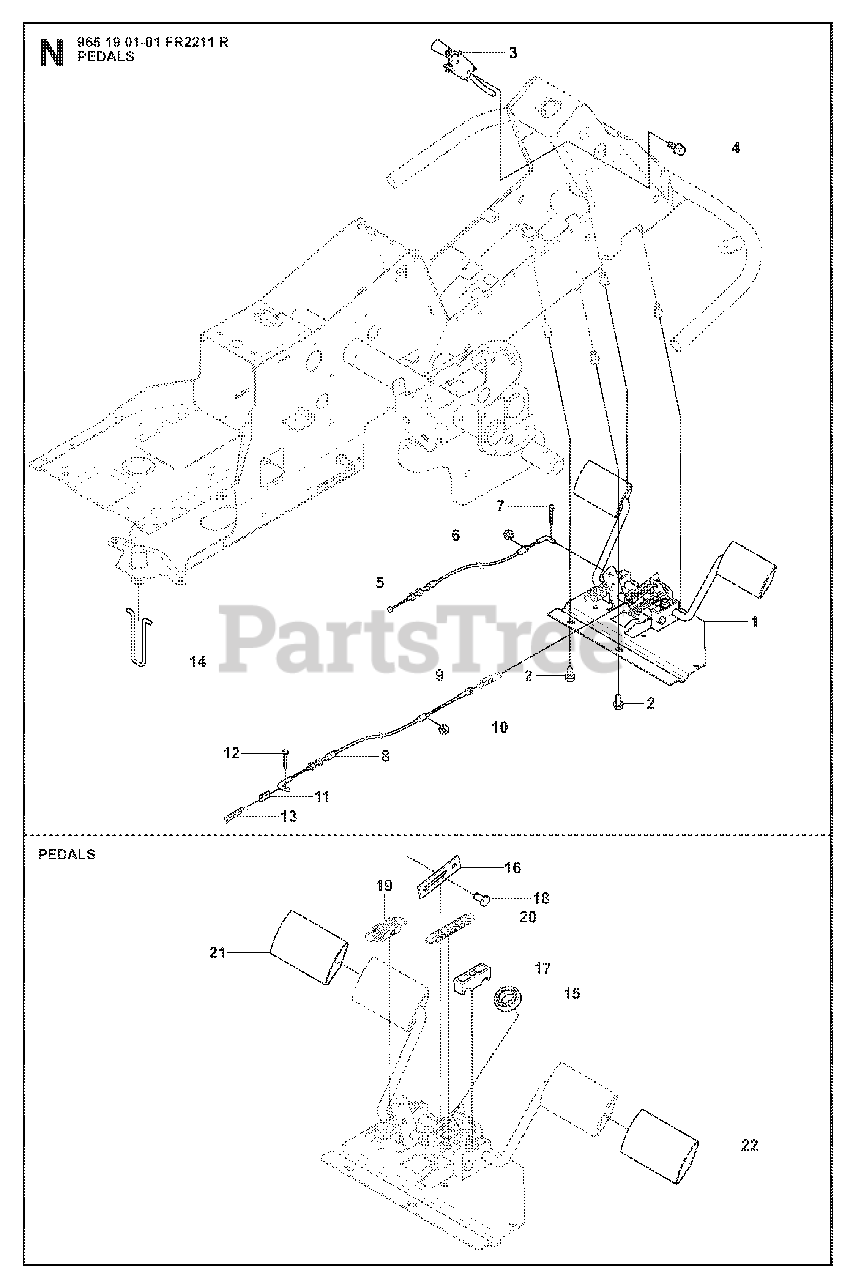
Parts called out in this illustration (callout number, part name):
3	BRAKE LEVER ASSY
7	COTTER PIN
11	CONNECTOR
12	COTTER PIN
15	BALL BEARING 6002-2RS1
17	PEDAL SHAFT CLAMP
18	CLEVIS PIN
21	PEDAL RUBBER, SF
22	PEDAL RUBBER, SF
